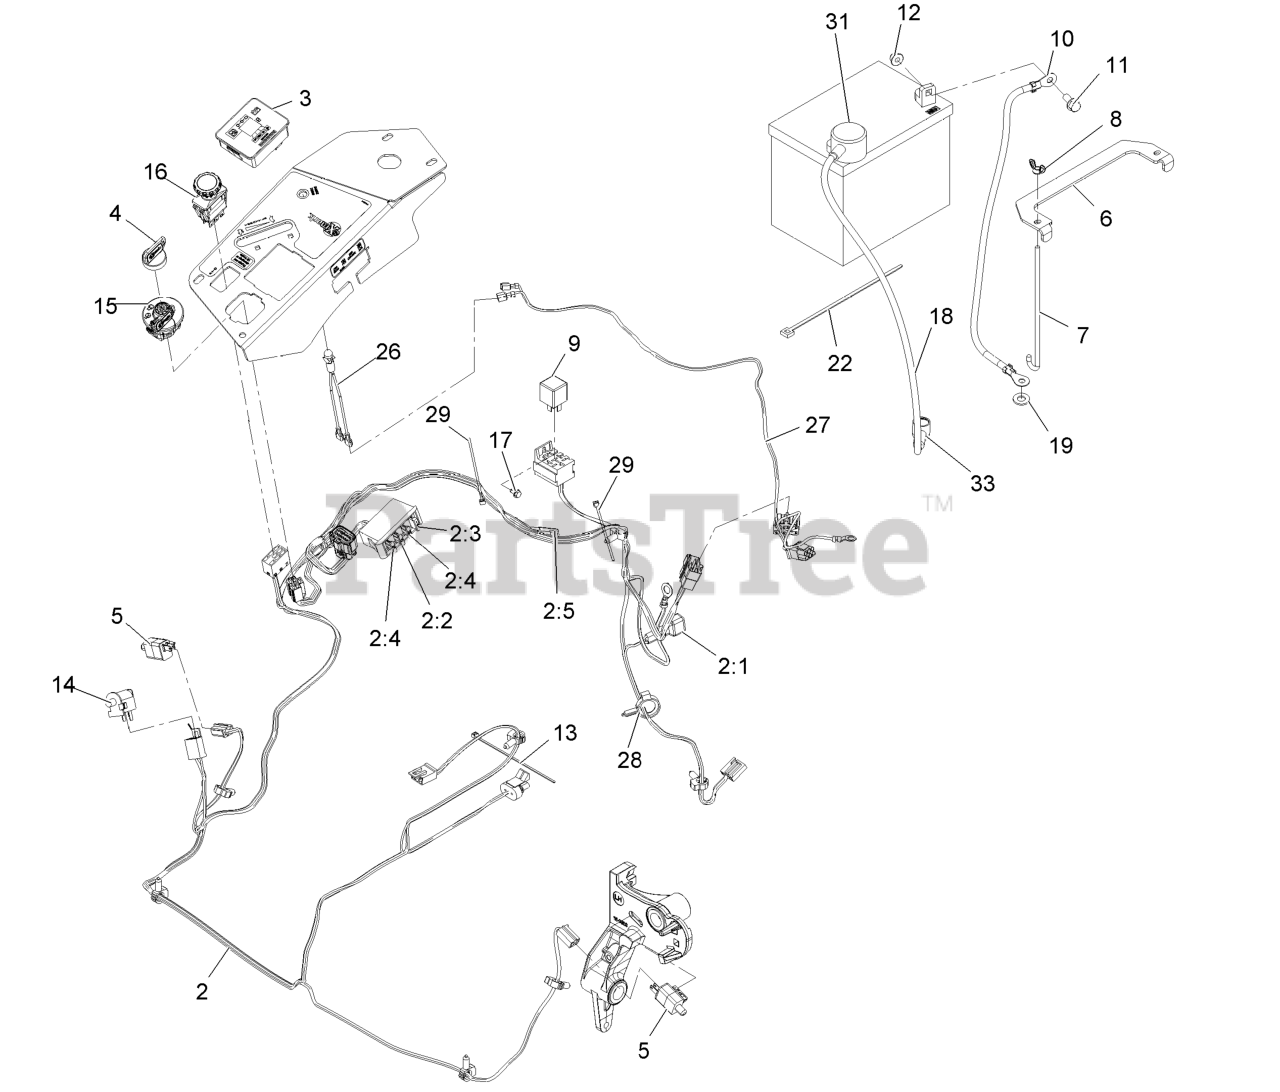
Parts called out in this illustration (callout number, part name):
2:2	FUSE-BLADE, 10 AMP
2:3	FUSE-BLADE, 15 AMP
2:4	FUSE-BLADE, 25 AMP
2:5	CAP-PLUG
3	FUEL/HOUR METER ASM
4	KEYS-IGNITION (SPARE PAIR
4	KEY-IGNITION
6	STRAP-TIE DOWN, BATTERY
7	BOLT-HOLDDOWN
8	WINGNUT
10	CABLE-BATTERY, NEGATIVE
11	SCREW-HHF
12	NUT-HF, NI
13	TIE-CABLE
14	SWITCH-BAIL
16	SWITCH-PTO, 10 AMP
17	SCREW-HWH
18	CABLE-BATTERY, POSITIVE
19	WASHER-FLAT
22	TIE-PLASTIC
26	INDICATOR-LED, RED
27	HARNESS-LIGHT, INDICATOR
28	CLAMP-HOSE
29	TIE-CABLE
31	INSULATOR-BATTERY
33	INSULATOR-SOLENOID
